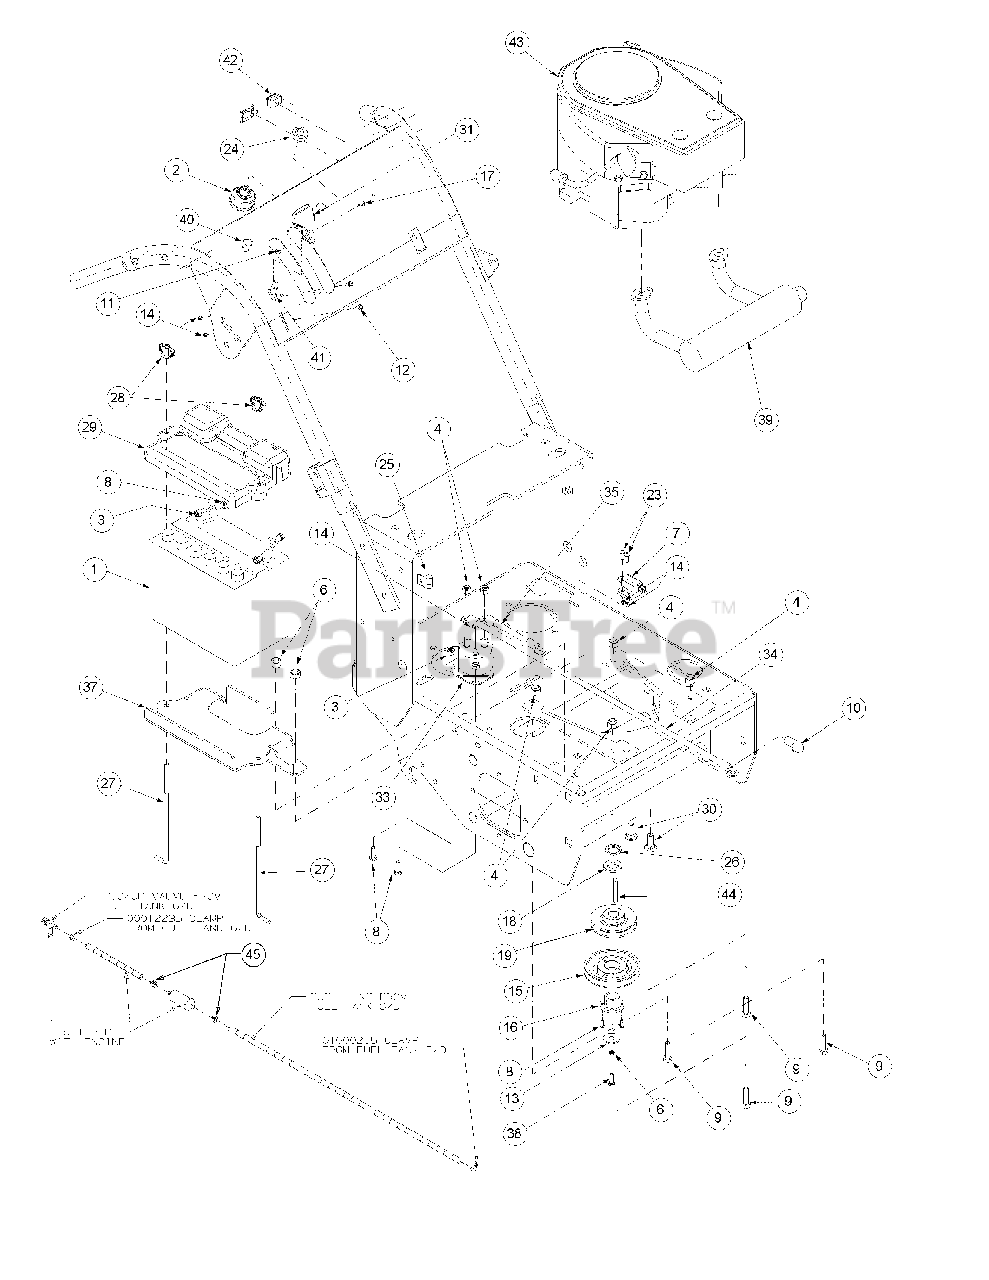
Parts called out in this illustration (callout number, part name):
1	Battery 12V
2	Ignition Switch
3	Lock Nut Nylon Insert, 1/4-20
4	Nylock Nut, 5/16-18
5	Nylock Nut, 3/8-16
6	Lock Washer, 7/16
7	Delta Switch
8	Hex Cap Screw, 1/4-20, .75
9	Hex Cap Screw, 5/16-18 x 2
10	Rubber Boot, 1" OD
11	Nut, 8-32, w/ star washer
12	Screw, Hex Washer w/slot, 10-32x1/2
13	Clutch Washer
14	Lock Nut, Nylon Insert, #10-32
15	Deck Pulley
17	Machine Screw, 8-32
18	Washer
19	Cast Pulley, 1" Bore
20	Hydro Pump Belt
21	Black Battery Cable, 17" Long
23	Machine Screw, 10 -32 x 5/8
24	Nut w/cap 5/8-32
25	Support Clamp 3/8 OD
26	Engine Pulley Spacer, 12.5
27	Battery Holdown Rod
28	Wing Nut, 1/4-20 w/Bell Washer
29	Battery Cover
30	Carriage Bolt, 3/8-16 x 1
31	Throttle Control Knob
32	Harness Hourmeter
33	Magnetic Solenoid Switch
34	24" Red Battery Cable
35	5" Red Battery Cable
36	Harness Adapter Kawasaki
37	Battery Bracket
38	Capscrew, 7/16-20 x 1-1/4
40	Cable Choke
41	Control Throttle w/Detent
42	Hour Meter includes:
43	17 HP Kawasaki Kai Engine
44	Bevel Key, 1/4 x 1/4 x 2.75
45	Hose Clamp, 1/4-5/8, SS
